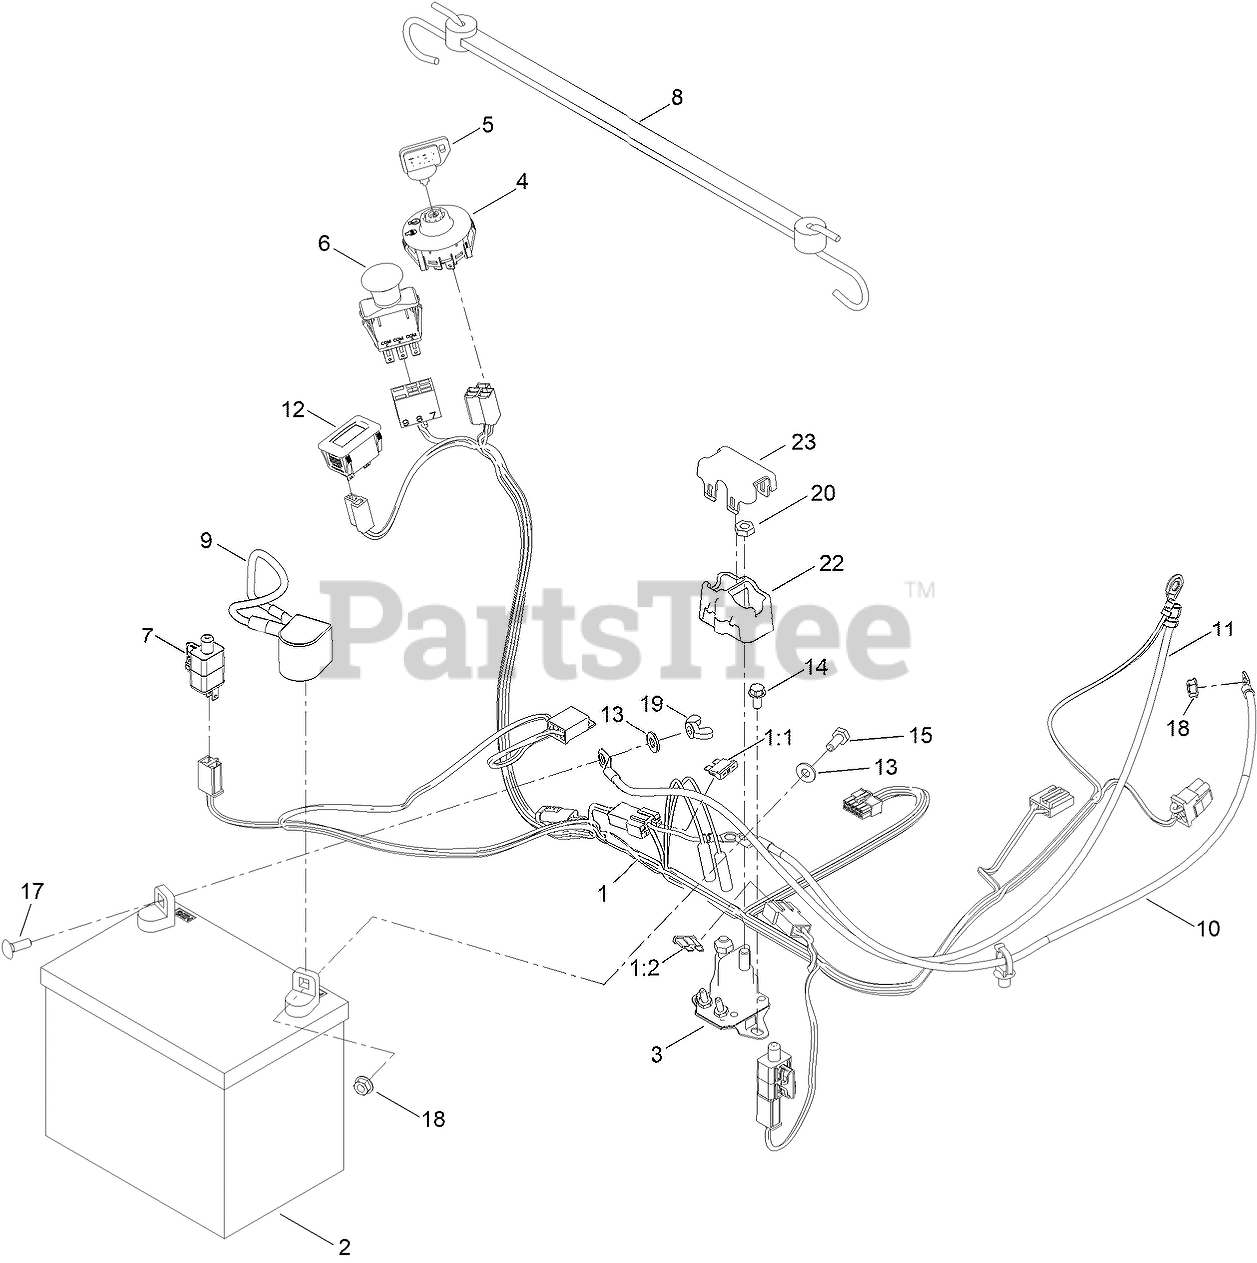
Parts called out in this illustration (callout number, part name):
1	HARNESS-WIRE
1:1	FUSE-BLADE, 15 AMP
1:2	FUSE-BLADE, 25 AMP
2	BATTERY
3	SOLENOID
4	SWITCH-IGNITION
5	KEY-IGNITION
6	SWITCH-PTO
7	SWITCH
8	STRAP-RUBBER
9	CABLE-BATTERY, POS
10	CABLE-BATTERY, RED (8 GAUGE)
11	CABLE-BATTERY, BLACK
12	HOURMETER
13	WASHER-FLAT
14	SCREW-HWH
15	SCREW-HH
17	BOLT-CARR
18	NUT-HF
19	NUT-WING
20	NUT-JAM
22	COVER-SOLENOID
23	CAP-SOLENOID
